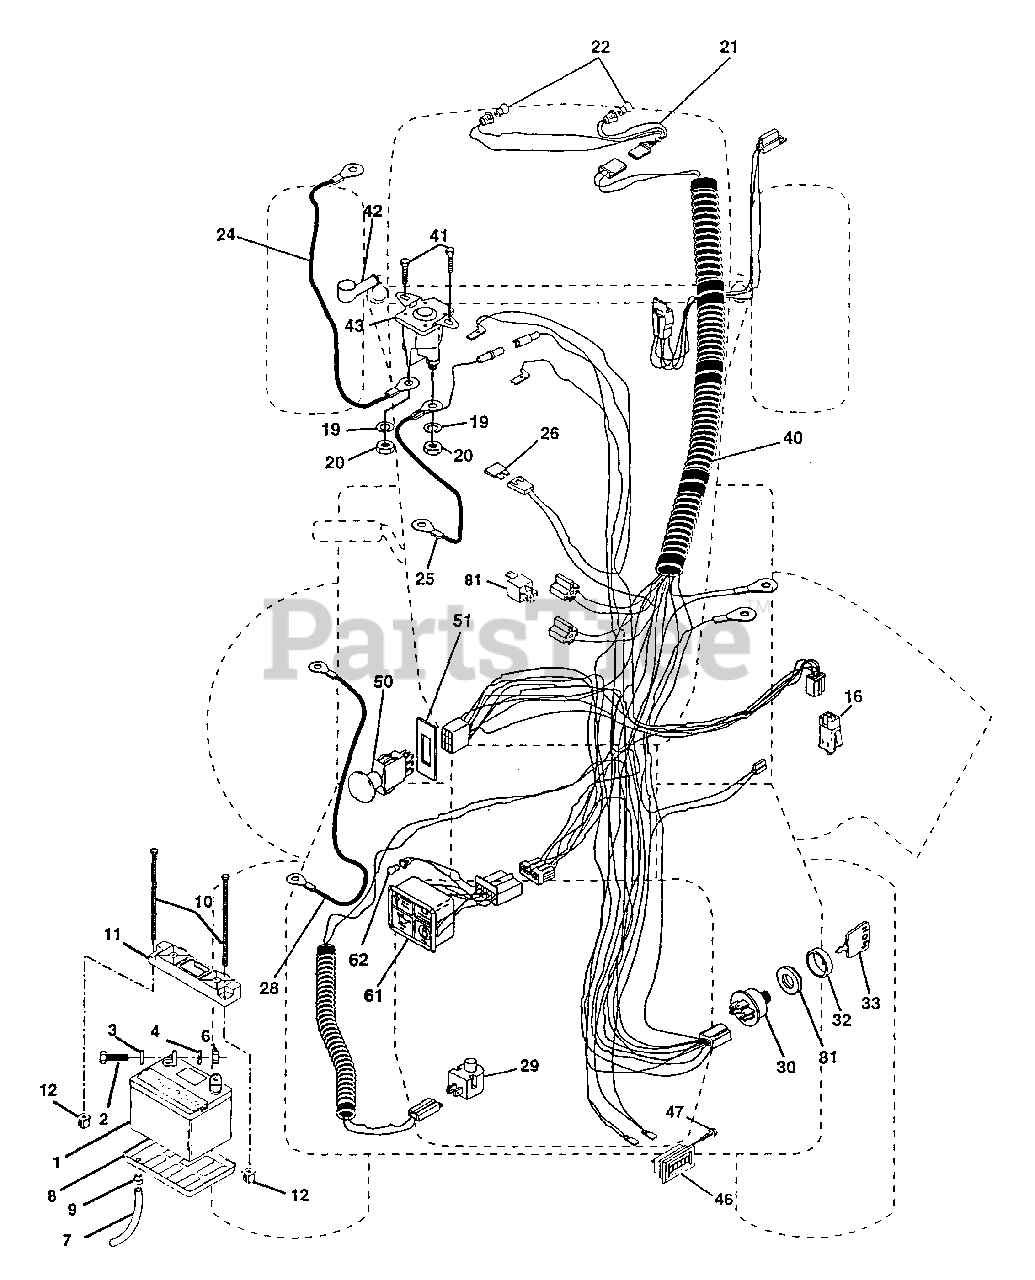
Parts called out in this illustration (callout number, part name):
1	Battery (AYP part number)
2	Bolt Hex Head 1/4-20 x 3/4
3	Washer, Lock 1/4
4	Washer 9/32 x 5/8 x 16 Ga
6	Nut Fin Hex 1/4-20
7	Tube Plastic
8	Tray, Battery
9	Clamp, Hose
10	Bolt, Battery Front 1/4-20 x 7.5 Zinc (AYP part number)
11	Holddown Battery Front Mount
12	Nut, Push Nylon 1.4" Battery Front (AYP part number)
16	Switch Interlock Push-In (AYP part number)
19	Washer, Lock 1/4 (AYP part number)
20	Nut, Jam Hex 1/4-20
21	Harness Socket Light w/4152J
22	Bulb Light
24	Cable, Starter
25	Cable, Battery
26	Fuse
28	Cable, Ground
29	Switch, Plunger
30	Switch, Ign
31	Nut, Ignition Switch
32	Cover Switch Key
33	Key
40	Harness Ign.
41	Screw 1/4-20 x 1/2
42	Cover, Terminal Red
43	Solenoid (AYP part number)
46	Meter Hour
47	Screw #10-24 x 1/2
50	Switch, PTO
51	Ring Retainer PTO
61	Light Pkg Asm
62	Bulb, Light Pkg. (AYP part number)
81	Relay Asm.
